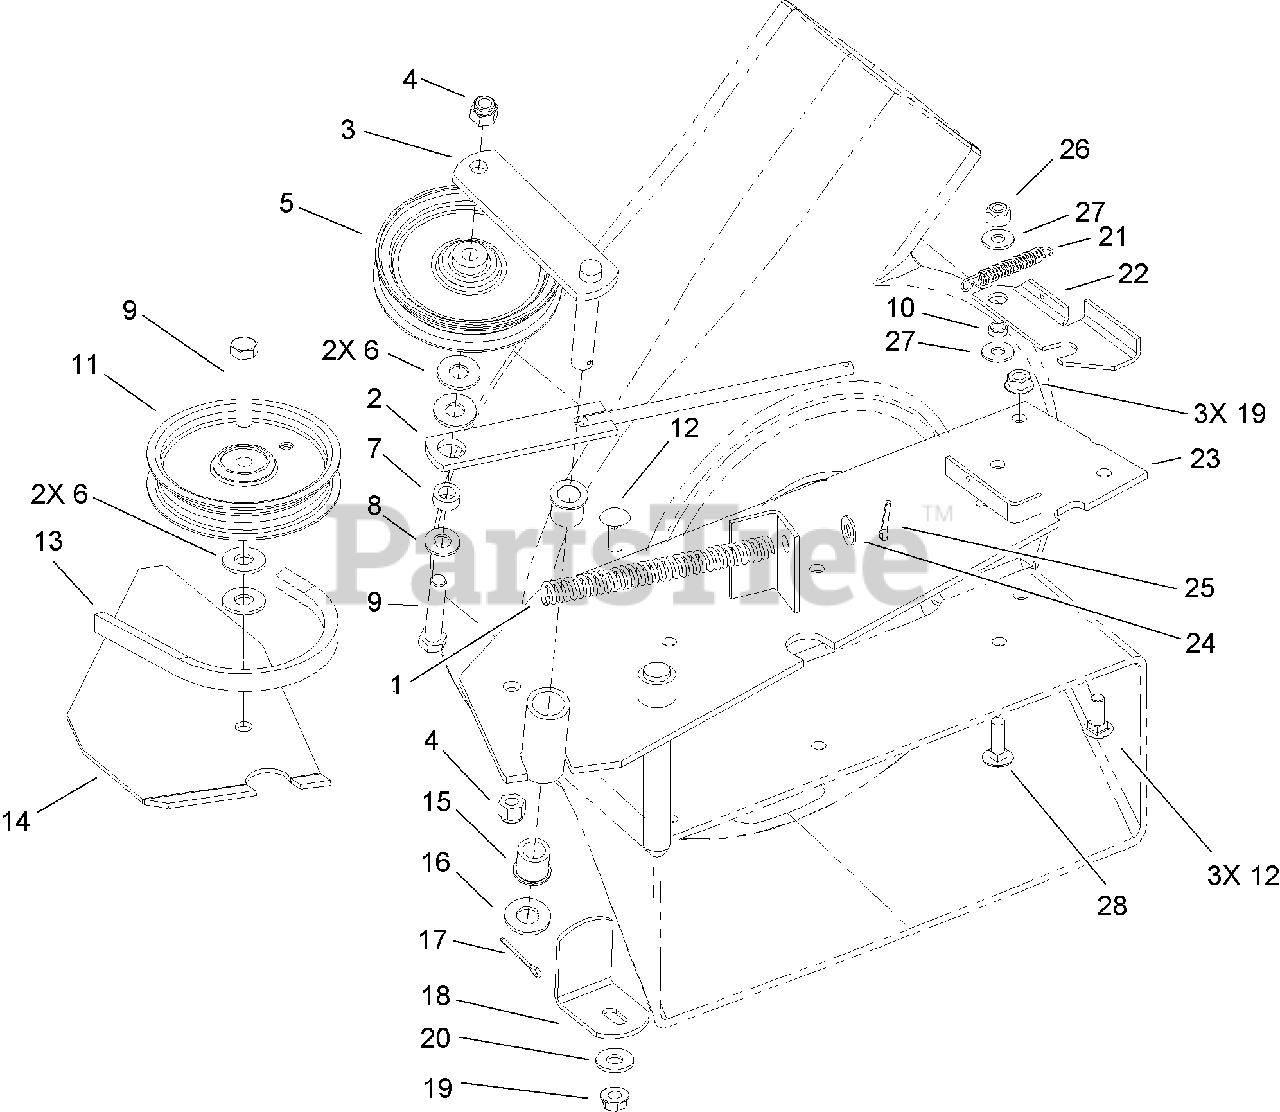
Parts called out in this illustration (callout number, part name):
1	SPRING-COMPRESSION
2	SPRING-ROD
3	IDLER ARM ASM
4	NUT-LOCK, NI
5	PULLEY-IDLER
6	WASHER-FLAT
8	WASHER-FLAT
9	SCREW-HH
11	PULLEY-IDLER
12	SCREW-CARR
14	SUPPORT-SHIELD, BELT
15	BUSHING
16	WASHER-FLAT
17	PIN-COTTER
18	BRACKET-SUPPORT, HOUSING
20	WASHER-FLAT
21	SPRING-EXTENSION
22	Latch-Blower
23	Mounting-Blower
24	WASHER-FLAT
25	PIN-COTTER
26	NUT-LOCK, NI
27	WASHER-FLAT
28	BOLT-CARR
